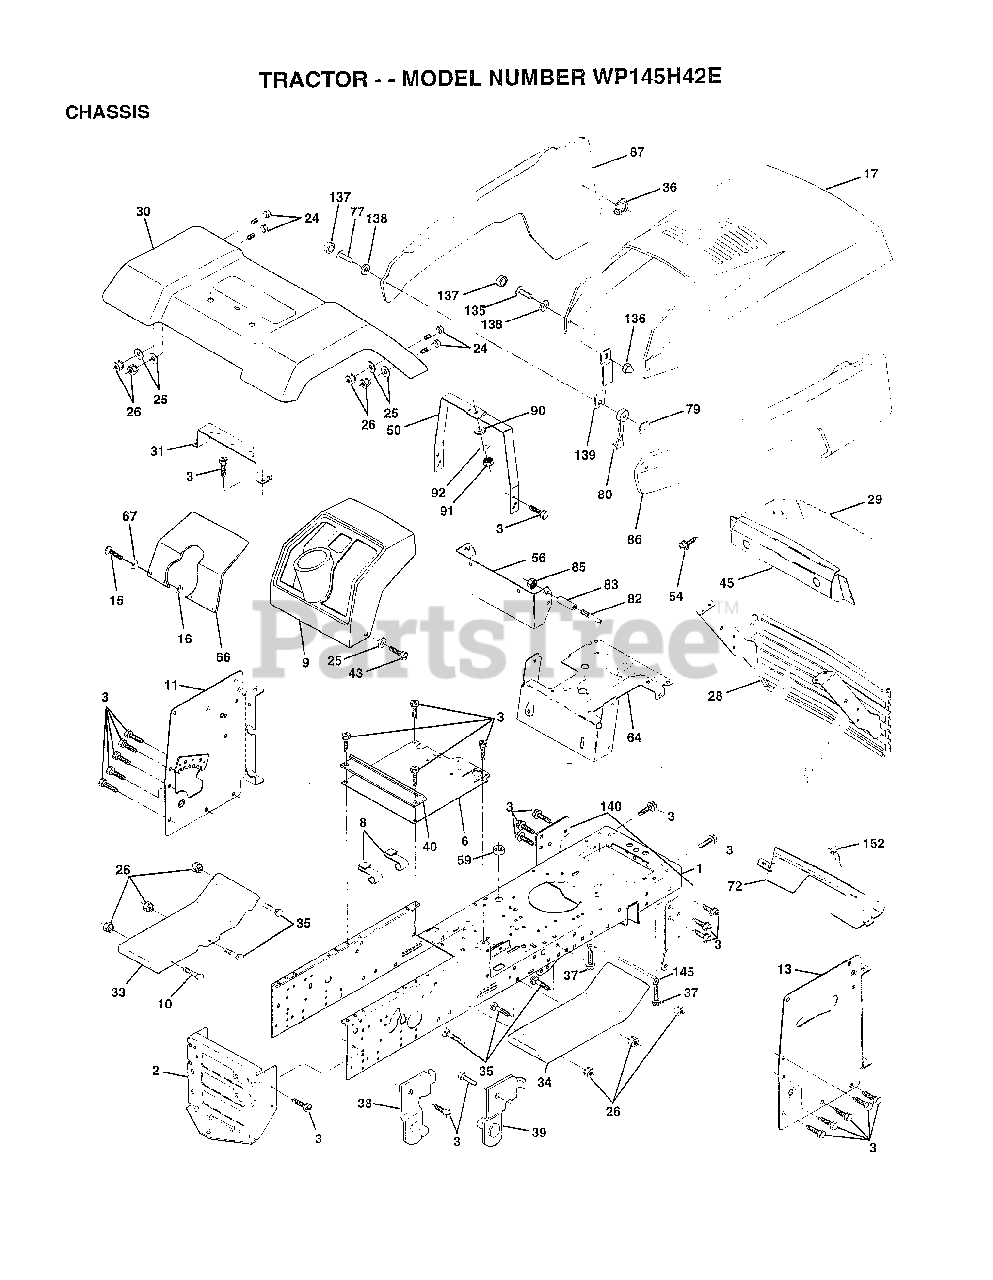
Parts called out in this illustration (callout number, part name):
3	SCREW
6	SADDLE
8	"CLIP,INSULATOR"
9	DASHBOARD BLACK
11	PANEL.DASH.LH.
13	PANEL.DASH.RH.
15	SCREW
24	BOLT
25	WASHER
26	NUT
28	GRILLE ASM PNT
29	PANEL.DASH.RH
30	FENDER.PNT.ASSY
31	BRACKET SUPT FEND
33	FOOTREST.LH.LT/GT
34	FOOTREST.RH.LT/GT
35	BOLT
36	PAL NUT LT
38	BRACKET ASM LH
39	BRACKET ASM RH
40	SPACER FENDER LT
43	SCREW GTV
45	BEZEL.1 PC
50	DASH.SUPT.YP/HUSQ
54	SCREW.HEX.WS.HD
56	EXT DASH LTYT
64	DASH.LOWER.LT
66	"PLATE-DASH,SLSCR"
67	WASHER
72	STRAP.GRILLE.PNT.
77	SCREW
79	WELDNUT
80	HOOD LATCH T
82	SCREW
87	"PANEL SIDE,LH"
90	WASHER PM
92	LOCKWASHER
135	SCREW.10-24X3/8.
136	ACORN NUT RB
137	SNAP CAP LT
138	WASHER LT
139	BKT.SPT.HOOD/PANL
140	BRKT SUSPENSION
145	"ROD POVOT,CHASSIS"
152	SCREW
